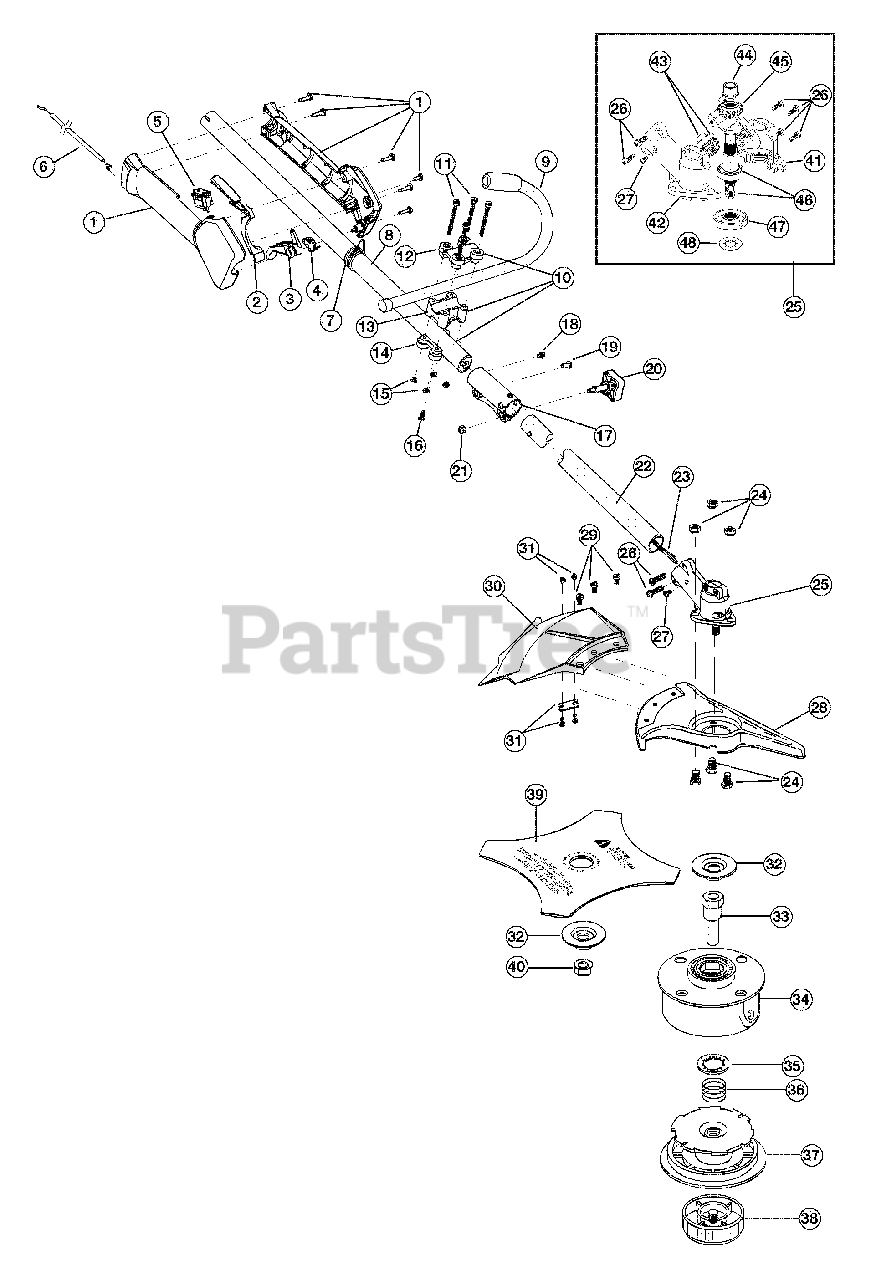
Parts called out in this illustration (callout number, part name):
1	Throttle Housing Assembly
2	Throttle Trigger Lock-Out
3	Throttle Trigger
4	Throttle Trigger Spring
5	Switch Assembly
6	Throttle Cable Assembly
7	Harness Clip
8	Upper Drive Shaft Housing Assembly
9	J-Handle Assembly
10	Handle Bracket Assembly
12	Upper Handle Clamp
13	Middle Handle Clamp
14	Lower Handle Clamp
16	Anti-Rotation Screw
17	Split Boom Coupler
20	Adjustment Knob
21	Knob Retaining Nut
22	Lower Drive Shaft Housing Assembly
23	Lower Flexible Drive Shaft
24	Shield Mount Screw Assembly
25	2 piece Gearbox Assembly
26	Gearbox Mounting Hardware
27	Anti-Rotation Screws
28	Blade Shield/Shield Mount
29	Shield Mounting Screw
30	Shield Assembly
31	Blade Assembly
32	Retaining Washer
33	Spool Shaft
34	Outer Spool Assembly
35	Retainer
37	Inner Reel
38	Bump Head Knob Assembly
39	4-Tooth Blade
40	Nut
41	Left Housing
42	Right Housing
43	Pinion Gear Assembly
44	Output Shaft Bushing
45	Output Shaft Gear
46	Output Shaft Assembly
47	Blade Driver
48	Palnut
